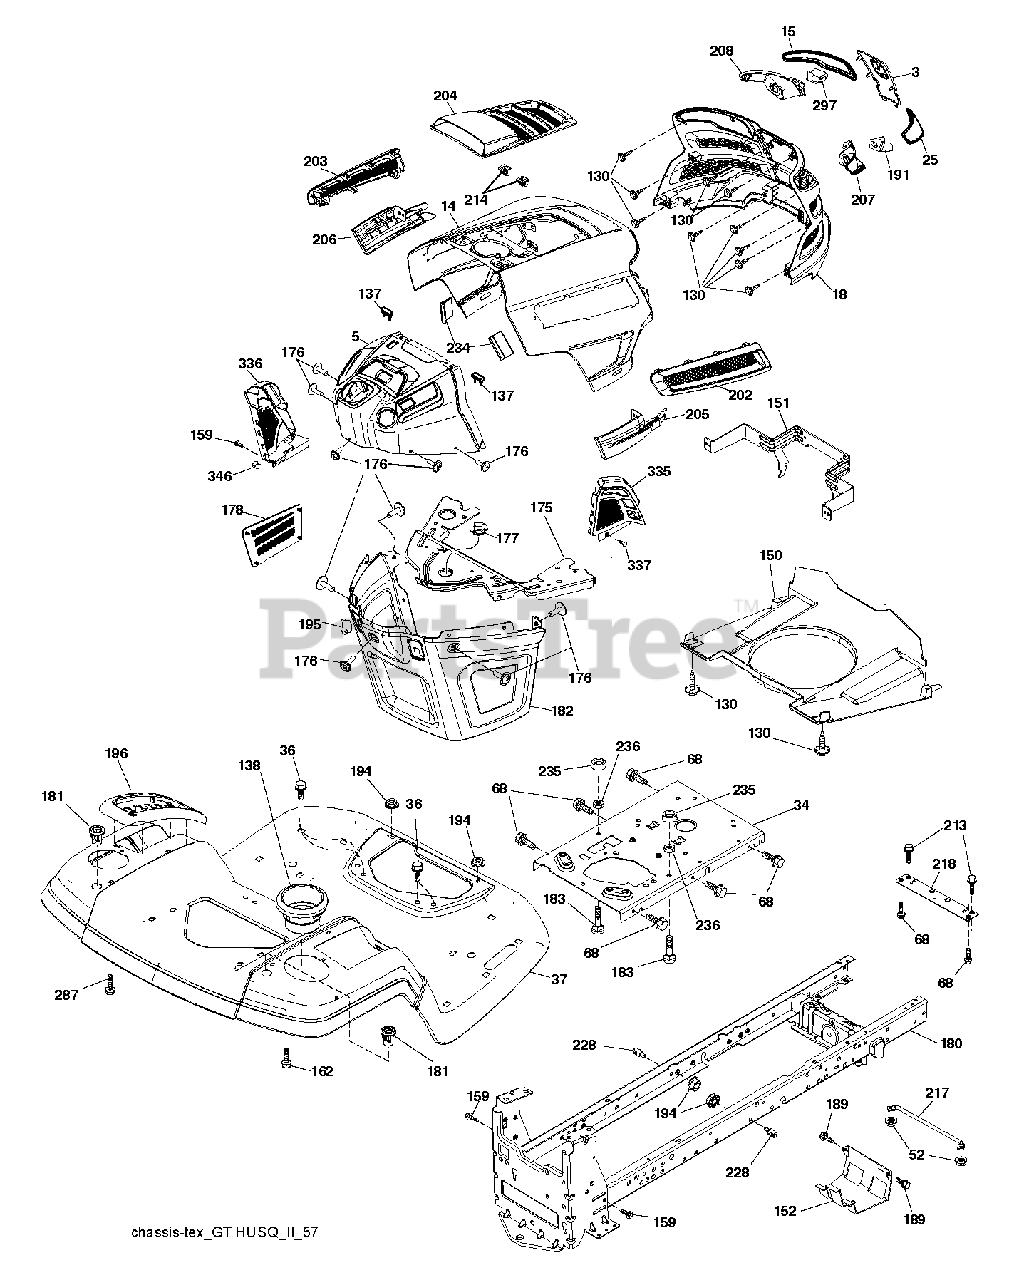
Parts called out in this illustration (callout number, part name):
3	APPLIQUE.SUBASM.GT.HUSQ.II
5	RP.DASH.UPP.GT2.SM.MC.CHOKE
14	HOOD.ASM.HUSQVARNA.GT.TEX.ORAN
15	LENS.HEADLIGHT.LH.GTII.2011
18	GRILLE.SUBASM.GT.HUSQ.II
25	LENS.HEADLIGHT.RH.GTII.2011
34	PLATE.ENGINE.WELDED.CHASSIS
36	SCREW 5/16"
37	FENDER.TLT.PDL.CNTRL.W/CPH.ORG
52	LOCKNUT
68	SCREW LT
130	SCREW.#10 X 0.750.BOS
137	BUMPER DASH
138	CUPHOLDER.TL.TEX.BLACK
150	AIR DUCT.GTV2(1.66"RING HEIGHT
151	BRACKET.PIVOT.HOOD.GT.HUSQ.II
152	SHIELD.BROWNING.PNT.GT.V2
159	SCREW, 3/8-16X3/4
162	SCREW.HI-LO.CONSOLE
175	PLATE.CROSSMEMBER.HUSQ
176	SCREW.#10-24X5/8.RN.QU
177	BUSHING, STEERING
178	CARGO.ASM.NET.TXGT.W/C
180	CHASSIS
181	BUSHING.MNT.FEND.CRGO.TEX.49
182	DASH.LOWER.COMMON.12V.ADAPTOR
183	BOLT.5/16-18X1-1/4 FULL THD
189	SCREW
191	INSERT.REFLECTIVE.RH.HUSQ.GTII
194	NUT LOCK HEX FLANGE 5/16-18
195	PLUG.HOLE.DASH.LOWER.12V.BLK
196	DECKLFT.CONSOL FULL ASSM GREY
202	VENT.SIDE.RH.GT.HUSQ.II.
203	VENT.SIDE.LH.GT.HUSQ.II.498
204	VENT.TOP.HUSQ.GT2
205	SIDE.TRIM.RH.GT.HUSQ.II
206	SIDE.TRIM.LH.GT.HUSQ.II.GRAY
207	BEZEL LIGHT.RH.GT.II.MYLAR
208	BEZEL LIGHT.LH.GT.II.MYLAR
213	BOLT
214	CLIP.RETAINER.TINNER.
217	ROD.PIVOT.HOOD
218	X-PIECE.HOOD.STOP.NON/
228	STUD.FASTNER.W/ANTI-ROTATE
234	BUMPER.HOOD.TEX.HUSQVARNA
235	SPACER FENDER
236	NUT.CENTERLOCK.5/16-
287	SCREW 1/4X20
297	INSERT.REFLECTIVE.LH.HUSQ.GTII
335	COVER.RH.CLOSE.OUT.BLACK
336	COVER.LH.CLOSE.OUT
337	CLIP.XMAS.TREE.ITW.2622-00
346	CLIP,INSULATOR
